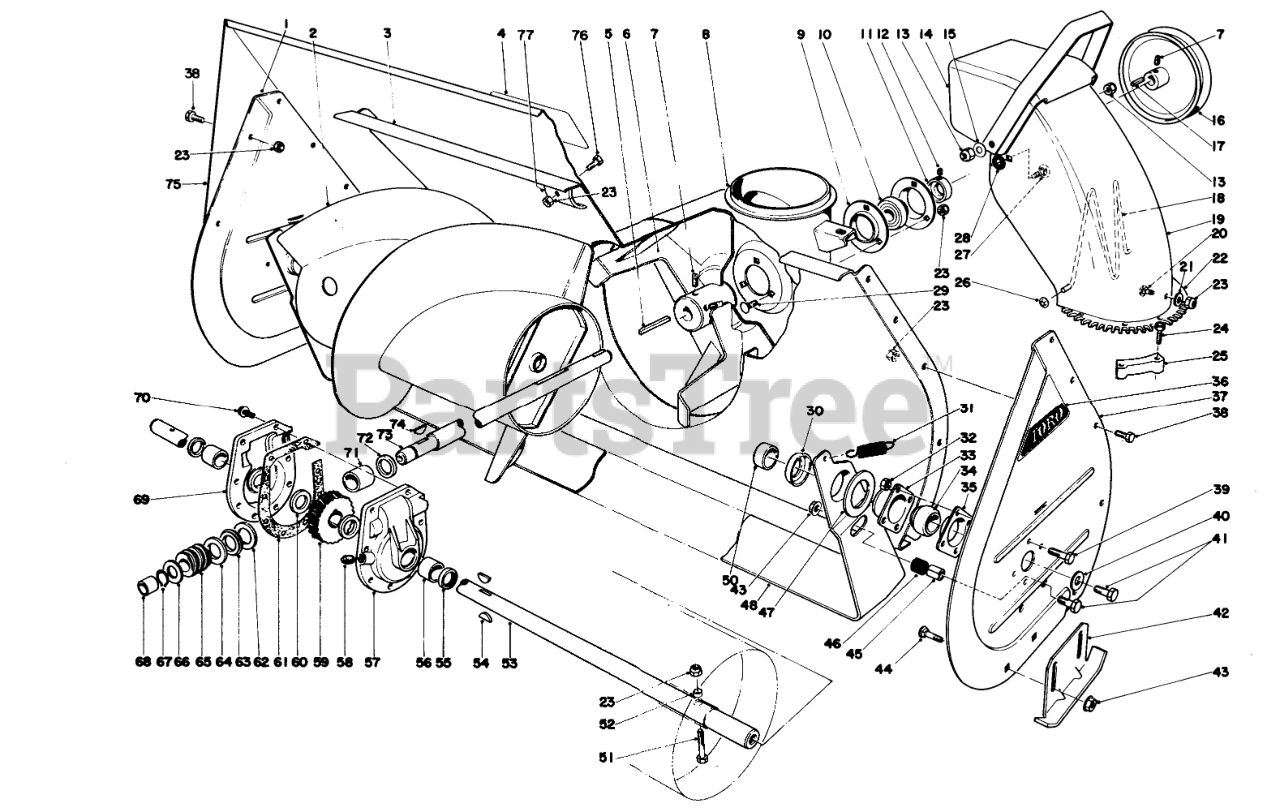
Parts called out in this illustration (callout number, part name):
1	RH AUGER SIDE PLT R
2	RH AUGER WA 26" B
3	AUGER HSG WA 26" R
4	Decal
6	IMPELLER ASM
7	SCREW-SET, SQH
8	CHUTE RING
9	BRG FLANGE
10	BALL BRG W/COLLAR
11	EXT LOCKING COLLAR
12	SCREW-HSH
13	NUT-LOCK, CONE
14	Deflector
15	WASHER-BELLEVILLE
16	1/2 X 9.5 DIA PULLEY
17	SQUARE KEY
18	WIRE-CHUTE
19	Upper Chute
20	SCREW-CARR
21	WASHER-PLAIN
22	Screw
23	NUT-LOCK, NI
24	SCREW-SPECIAL
25	RETAINER-CHUTE
26	NUT-PUSH
27	SCREW-CARR
28	WASHER-RUBBER
29	BOLT-CARR
30	Positioner-Scraper
31	SPRING-TENSION
32	NUT-LOCK, CONE
33	BEARING-FLANGE, FRONT
34	BEARING
35	BEARING-FLANGE, REAR
36	AUGER SIDE PLT DECAL
37	LH AUGER SIDE PLT R
38	SCREW-HH
39	SCREW-HH
40	WASHER
41	SCREW-HH
42	AUGER SKID WA R
43	NUT-HF
44	SCREW-CARR
45	SCRAPER STOP SPACER
46	SCRAPER STOP CUSHION
47	SCRAPER BLADE SPACER
48	SCRAPER BLADE 26 R
50	AUGER SPACER
51	Auger Bolt
52	SPACER-HUB, AUGER
53	26 AUGER SHAFT
54	KEY-WOODRUFF
55	SEAL-OIL
56	BUSHING
57	Gear Case L.H. (Incl. Ref. #55-56)
58	PLUG-PIPE, SQH
59	GEAR-WORM, 27T
60	WASHER-THRUST
61	asket
62	WASHER-THRUST
63	BEARING-THRUST
64	THRUST-WASHER
66	WASHER-THRUST
67	Ring-Snap
68	BUSHING
69	Gear Case R.H. (Incl. Ref. #55-56)
70	SCREW-TAPTITE
71	BUSHING-SPECIAL
72	RING-QUAD
73	SHAFT-IMPELLER
74	KEY-WOODRUFF
75	Auger Extension
76	SCREW-HH
77	SHIELD CLAMP R
